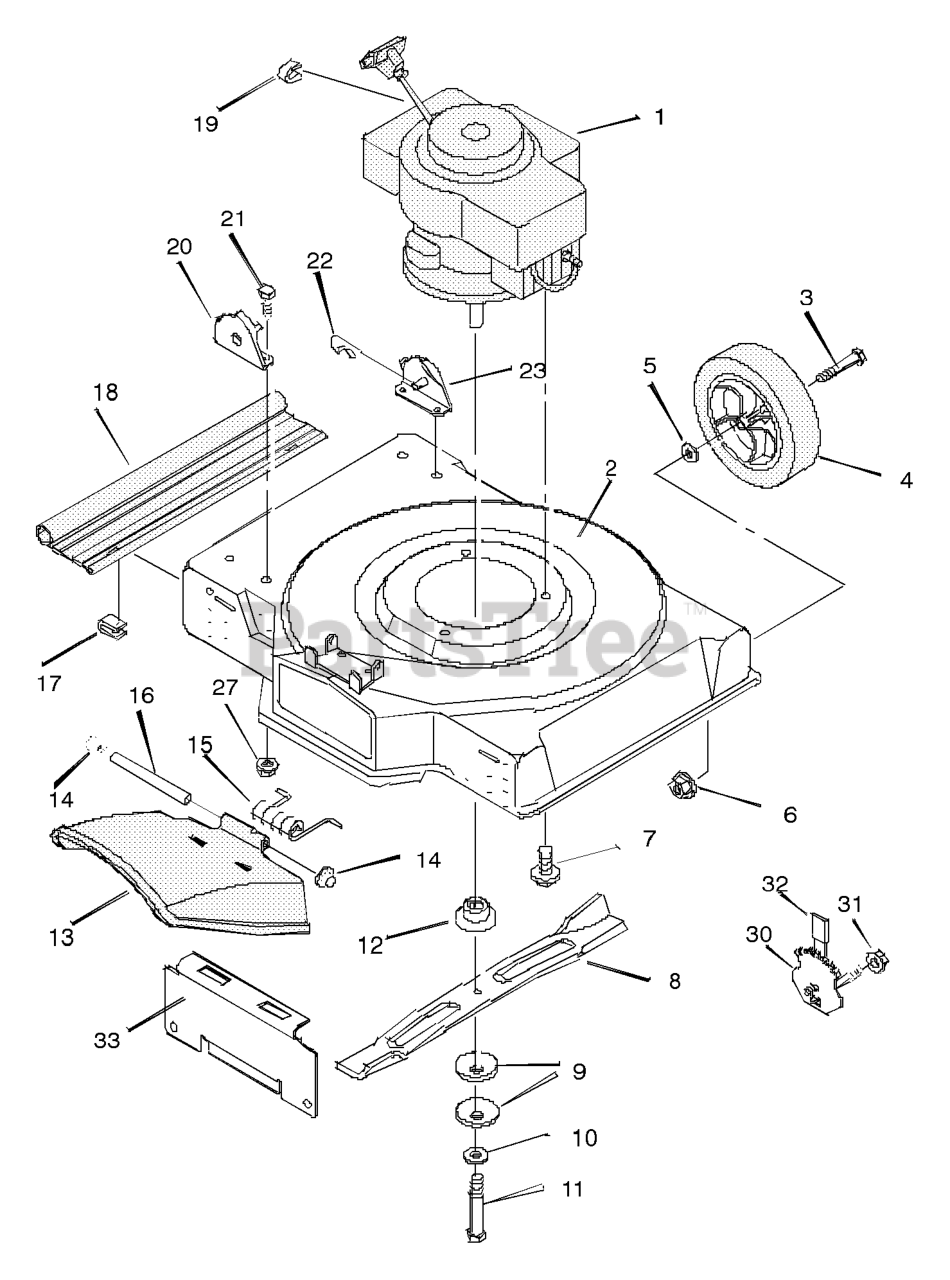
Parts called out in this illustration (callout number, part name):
1	Engine *
2	Housing
3	Bolt, Axle
4	Wheel and Tire *
6	Locknut, Flange
7	Bolt, Engine
9	Washer, Belleville
11	Bolt, Hex
12	Adapter, Blade
13	Deflector, Chute
14	Push-On Cap
16	Pin, Pivot
17	Retainer
18	Deflector, Rear
19	Stop, Rope
20	Bracket, Right Handle
22	Pin, Hair
23	Bracket, Left Handle
27	Nut
30	Adjuster, Height
31	Locknut, Flange
33	Plate, Mulcher
